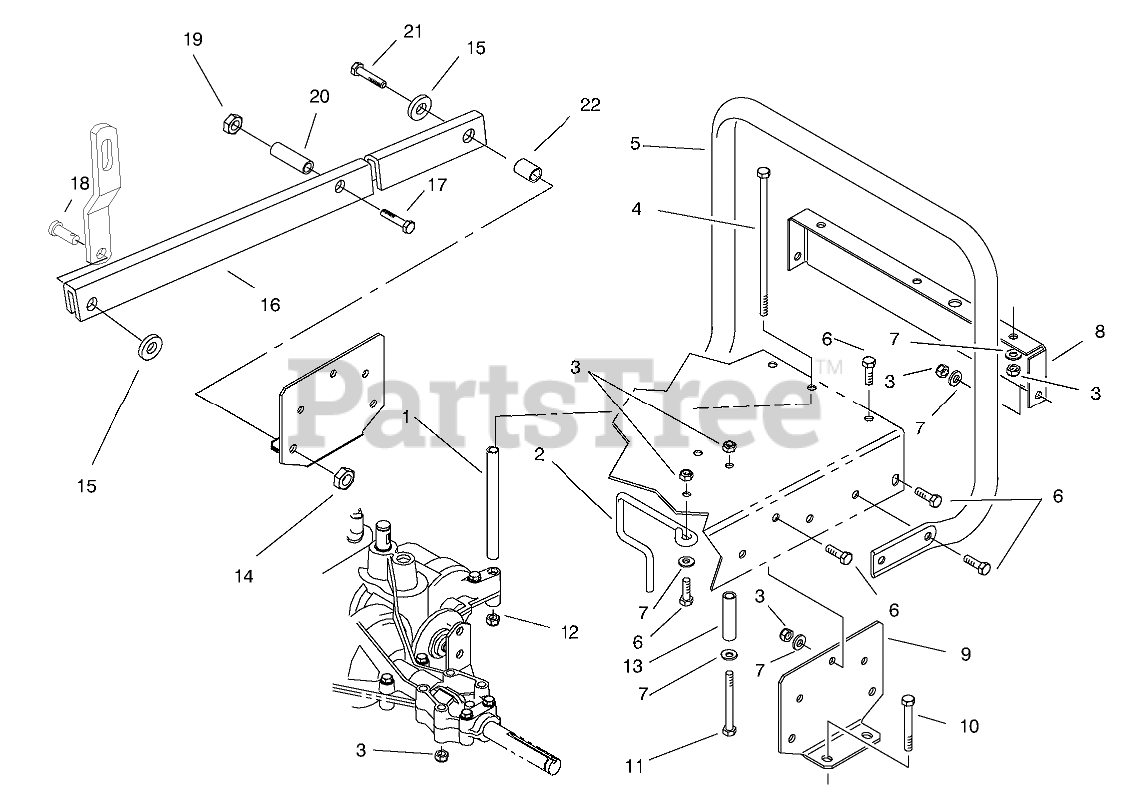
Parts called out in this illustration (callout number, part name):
1	SPACER-TRANSAXLE SUPT
2	GUIDE-ENG BELT
3	NUT-LOCK, NI
4	SCREW-HH
5	Standbar
6	SCREW-HH
7	WASHER-PLAIN
8	Frame-Rear
9	Support-Axle
10	SCREW-HH
11	SCREW-HH
12	NUT-LOCK, NI
13	SPACER-SPLIT TUBE
14	NUT-LOCK, NI
15	WASHER-FLAT
16	Arm-Suspension R.H.
17	SCREW-HH
18	PIN-CLEVIS
19	NUT-LOCK, NI
20	SPACER-SPLIT TUBE
21	SCREW-HH
22	PIN-SUPT ARM
